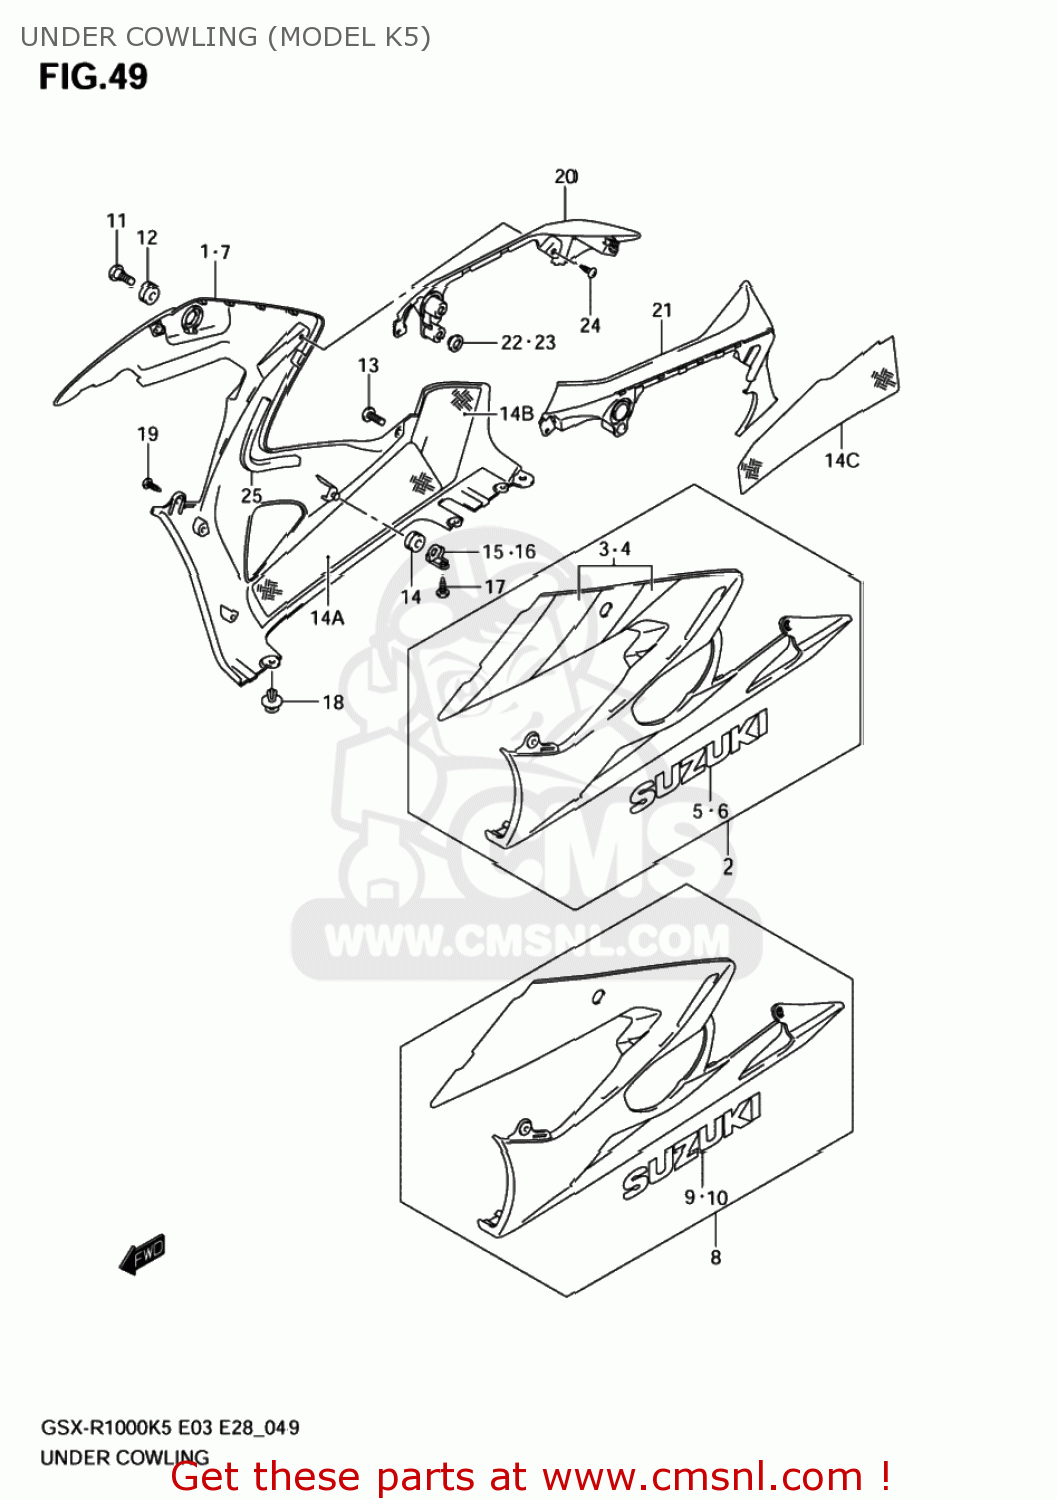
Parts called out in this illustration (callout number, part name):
1	COWLING,UNDER,R
2	COWL,UNDER,L F
3	TAPE SET,UNDER COWLING,R
4	TAPE SET,UNDER COWLING,L
5	EMBLEM,SUZUKI,R
6	EMBLEM,SUZUKI,L
7	COWLING,UNDER,R
8	COWLING
9	EMBLEM,SUZUKI,R
10	EMBLEM,SUZUKI,L
11	SCREW(6X20)
12	CUSHION
13	SCREW(5X13)
14	CUSHION
14A	SHIELD,HEAT UNDER NO.1,R
14B	SHIELD,HEAT UNDER NO.2,R
14C	SHIELD,HEAT UNDER,L
15	BRACKET,UNDER COWLING LWR,R
16	BRACKET,UNDER
17	BOLT
18	CLIP
19	SCREW
20	COVER
21	COVER
22	CUSHION
23	CUSHION
24	SCREW
25	CUSHION,UNDER COWLING,R
